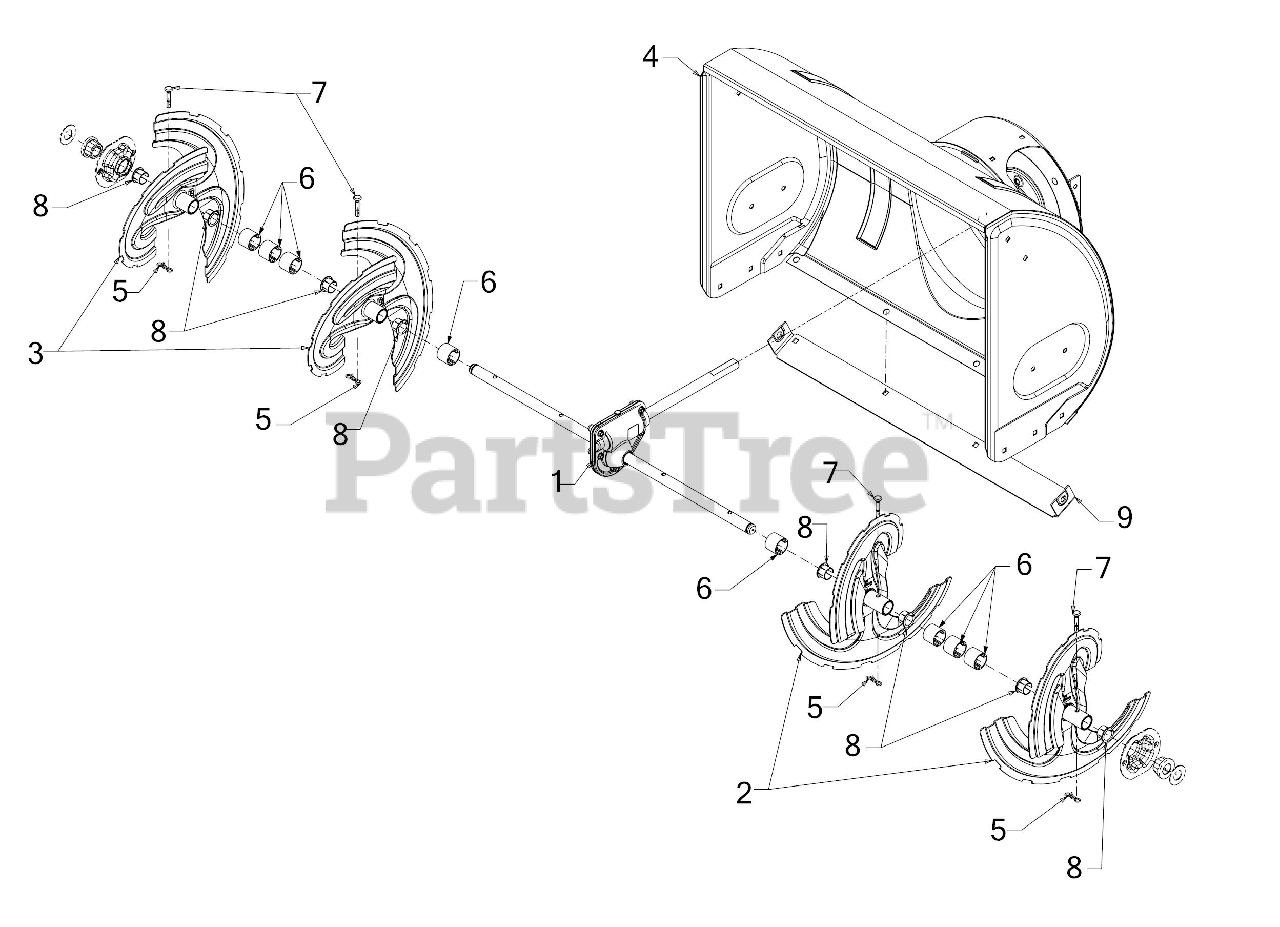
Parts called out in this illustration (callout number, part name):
1	28" GEARBOX ASSEMBLY
5	BOW TIE COTTER PIN 1/4-5/16
6	SPACER 1.25OD x .75ID X1.00 LG
7	SHEAR PIN .25 x 1.50 GR2
7	Cub Cadet SHEAR PINS (2X SNOW)
7	SHEAR PINS QTY 4
8	FLANGE BUSHING
